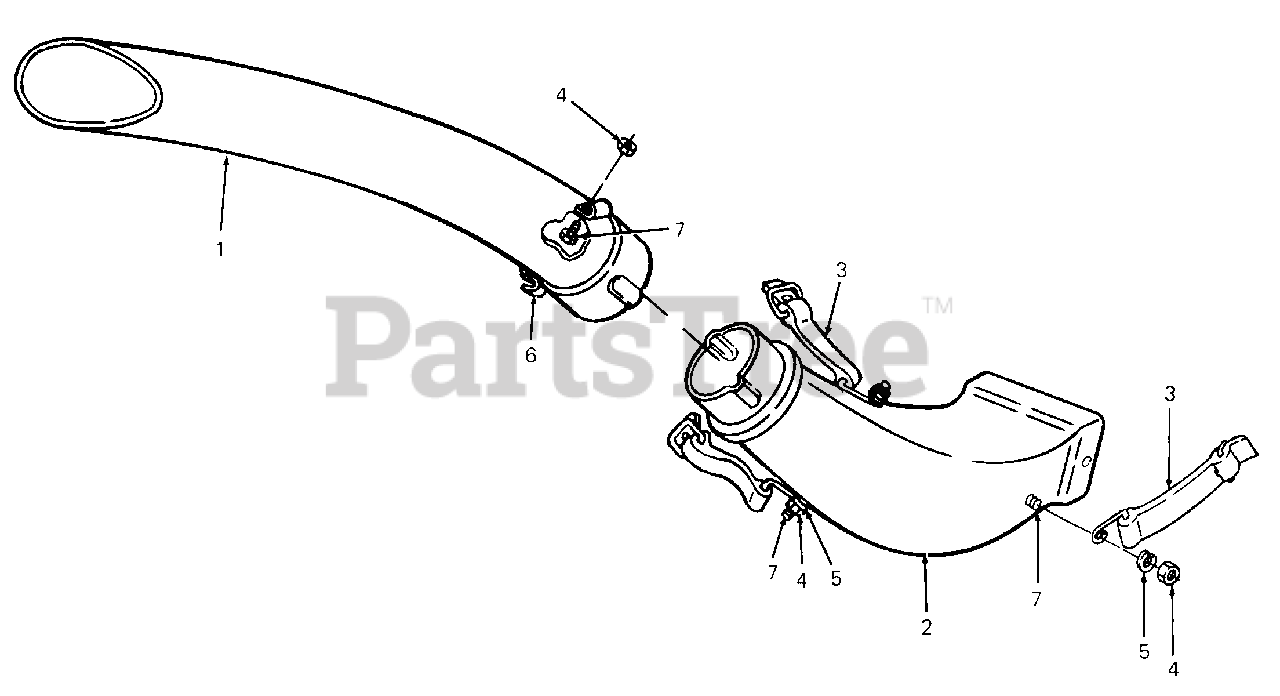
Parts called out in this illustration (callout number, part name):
1	Tube, Catcher
2	Chute, Discharge
3	Strap Assy, Retainer
4	Nut, Hex Insert Lock, 1/4-20
5	Washer, Spring, .265 ID x .562 OD
6	Hook Bracket, Retainer
7	Screw, Hex Cap, 1/4-20 x .62 Lg
